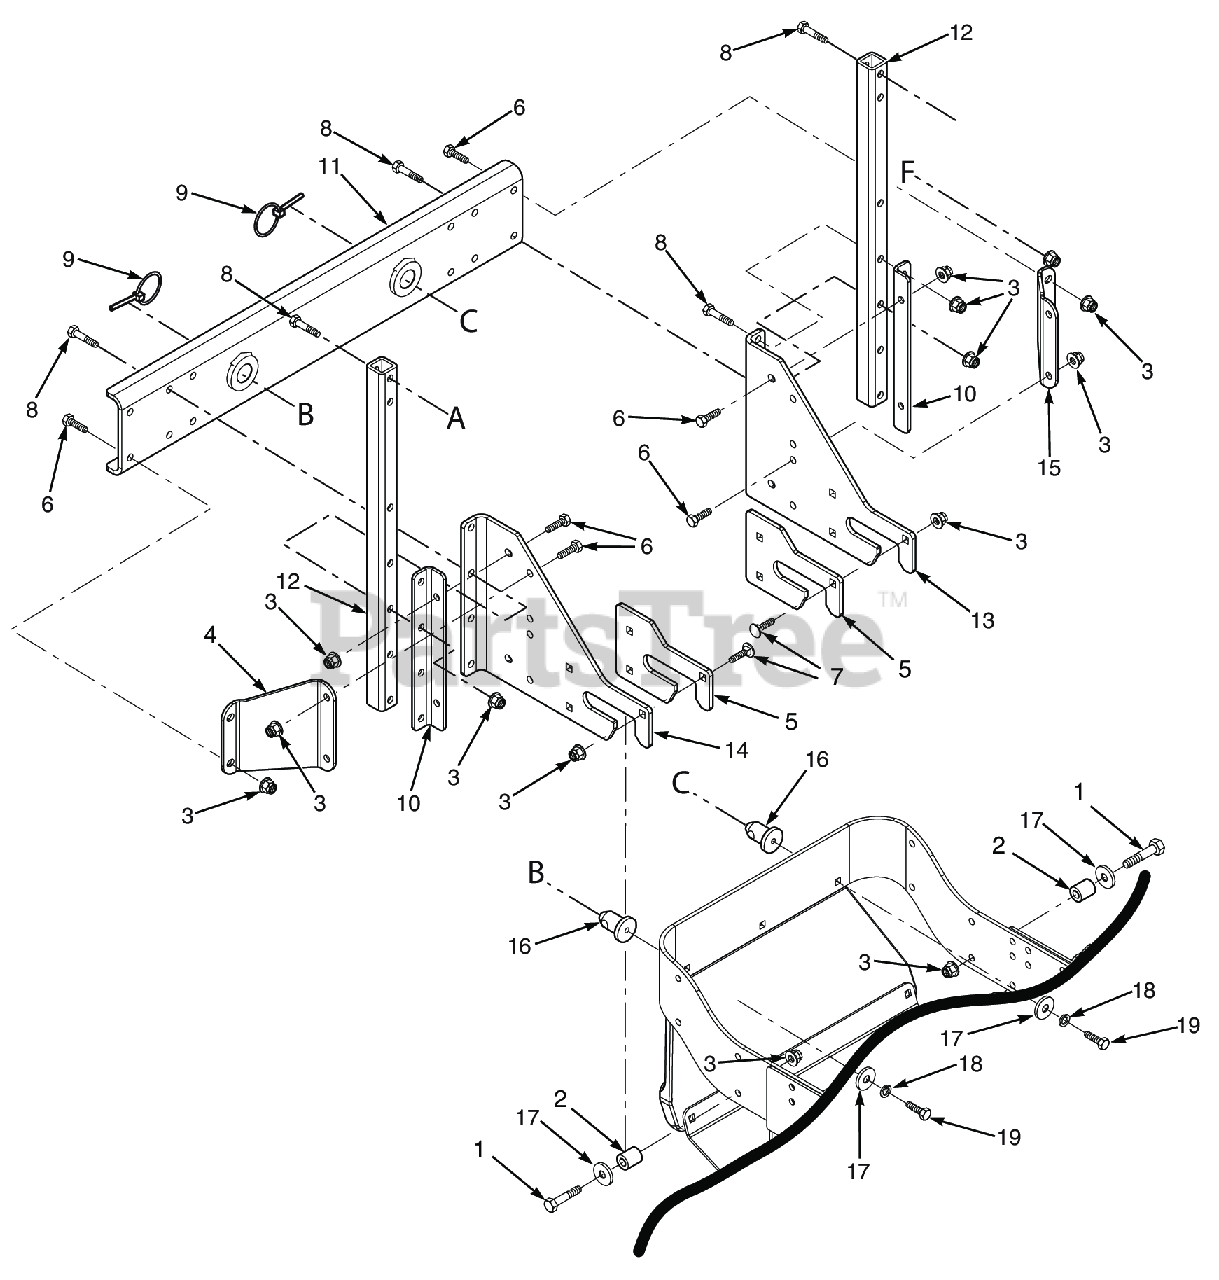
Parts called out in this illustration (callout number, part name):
1	Bolt, Hex Head 3/8-16 x 2-1/4" - 61"
2	Spacer
3	Nut, Flange Elastic Stop Nut, 3/8-16
4	Angle Bracket, GC
5	Wear Plate, GC
6	Bolt, Hex Head 3/8-16 x 1"
7	Carriage Bolt, 3/8-16 x 1-1/4"
8	Bolt, Hex Head 3/8-16 x 2-1/4" - 61"
9	Quick Pin, 5/16" Dia.
10	Mounting Bracket, Tube
11	Mounting Bracket Weldment
12	Tube, Upright
13	Mounting Bracket, GC R.H.
14	Mounting Bracket, GC L.H.
15	Angle Bracket, GC
16	Pin, GC Locator
17	Flatwasher, 3/8-.406 x 1-1-1/2 x 7 Gauge
18	Lockwasher, 3/8" Spring, Kawasaki FX / FS
19	Bolt, Hex Head 3/8-16 x 1-1/4", Kawasaki FX / FS
